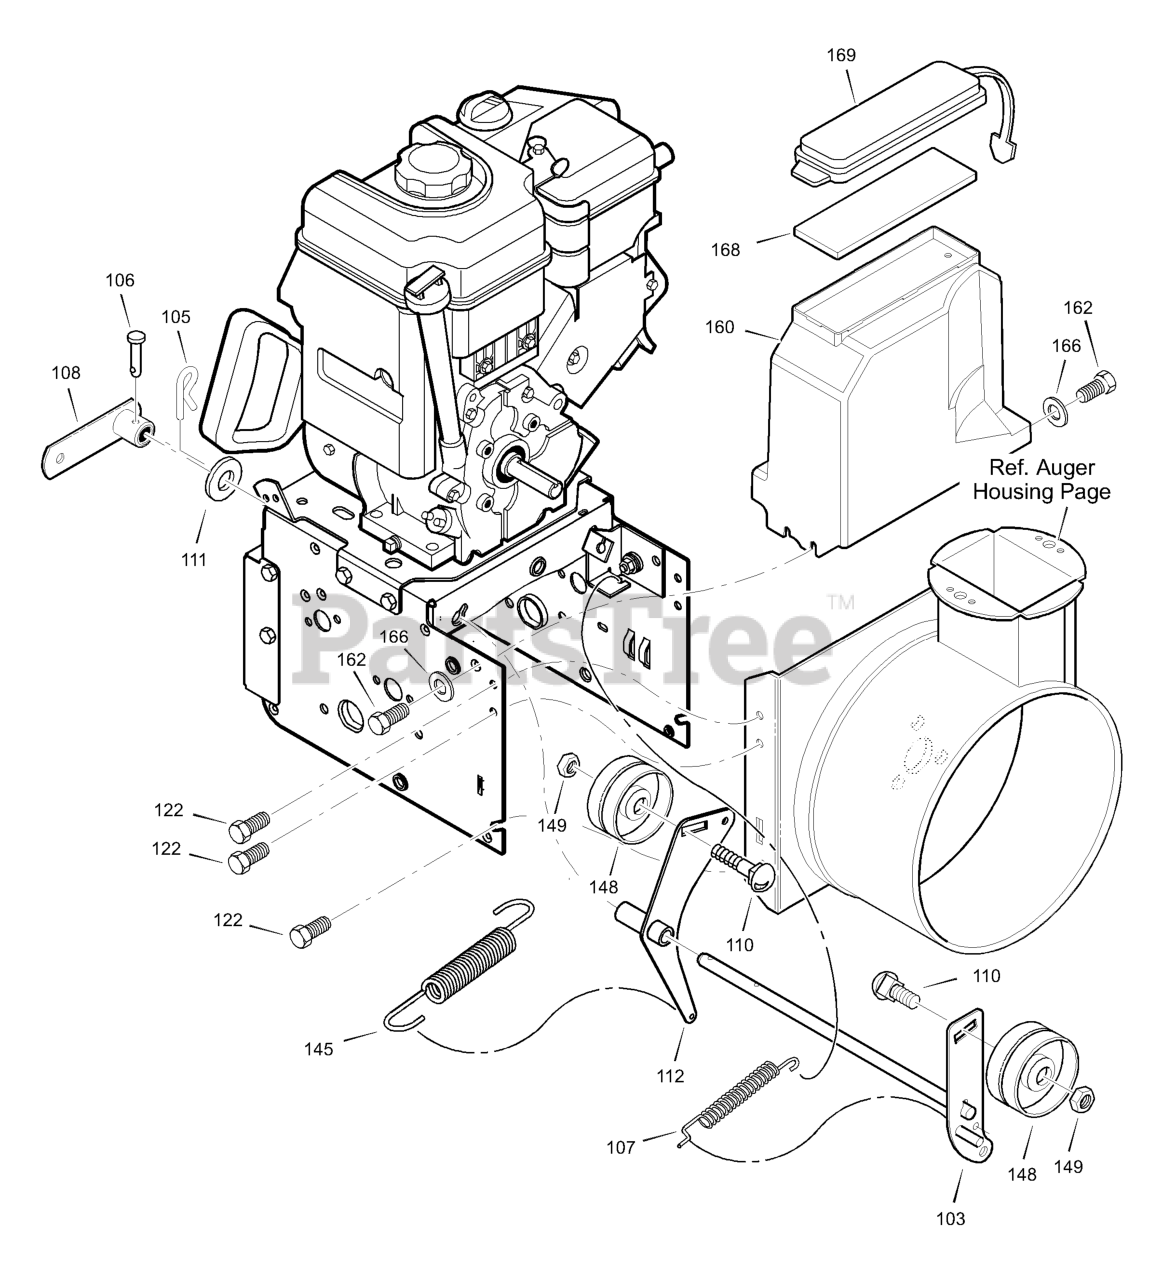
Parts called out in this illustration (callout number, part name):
103	IDLER ASSEMBLY, AUGER
105	PIN, HAIR
106	PIN, KLIK 3/16" DIA
107	SPRING, TENSION
108	ASSY., SPRING ATTACH
110	BOLT, 3/8-16X1.25 CARR.
111	WASHER, FLAT
112	BRACKET, DRIVE IDLER
122	SCREW, TAP 5/16-18 X .50
145	SPRING, CLUTCH
148	PULLEY, IDLER
149	NUT, JAM 3/8-16
160	COVER, BELT
162	SCREW, TAP 1/4-20 X .63
166	WASHER, FLAT
168	PAD, FOAM
